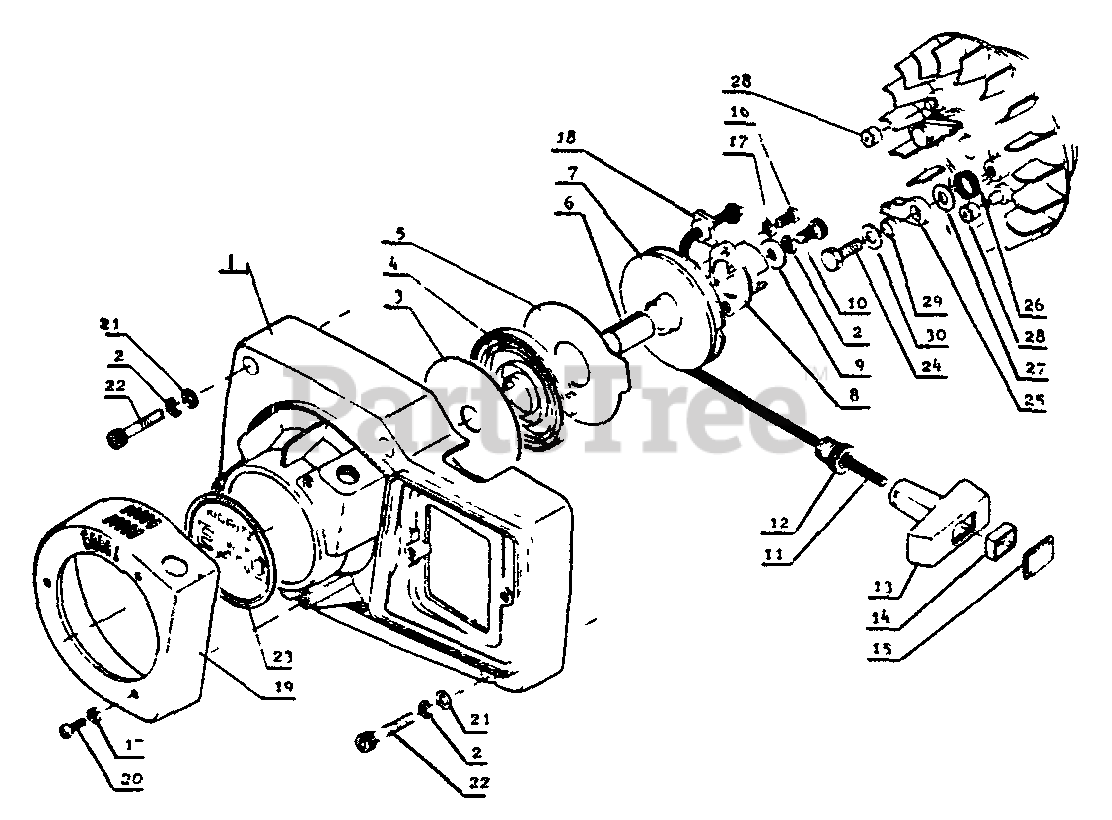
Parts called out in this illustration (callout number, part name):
1	CASE, STARTER
2	LOCKWASHER - 5
3	PLATE, STARTER
4	SPRING, REWIND
5	PLATE, STARTER
7	REEL, ROPE
8	CATCHER, PAWL
9	WASHER - 5
10	SCREW - 5X15
11	ROPE, STARTER
12	GUIDE, ROPE
13	GRIP, STARTER
14	RING, RETAINING
16	SCREW - 4X10
17	LOCKWASHER - 4
18	RETAINER, ROPE
19	FILTER, DEBRIS
20	SCREW - 4X8
21	WASHER - 5
22	SCREW - 5X30
23	NAME PLATE
24	BOLT - 6X16
25	PAWL, STARTER
26	SPRING, RETURN
30	WASHER - 6
